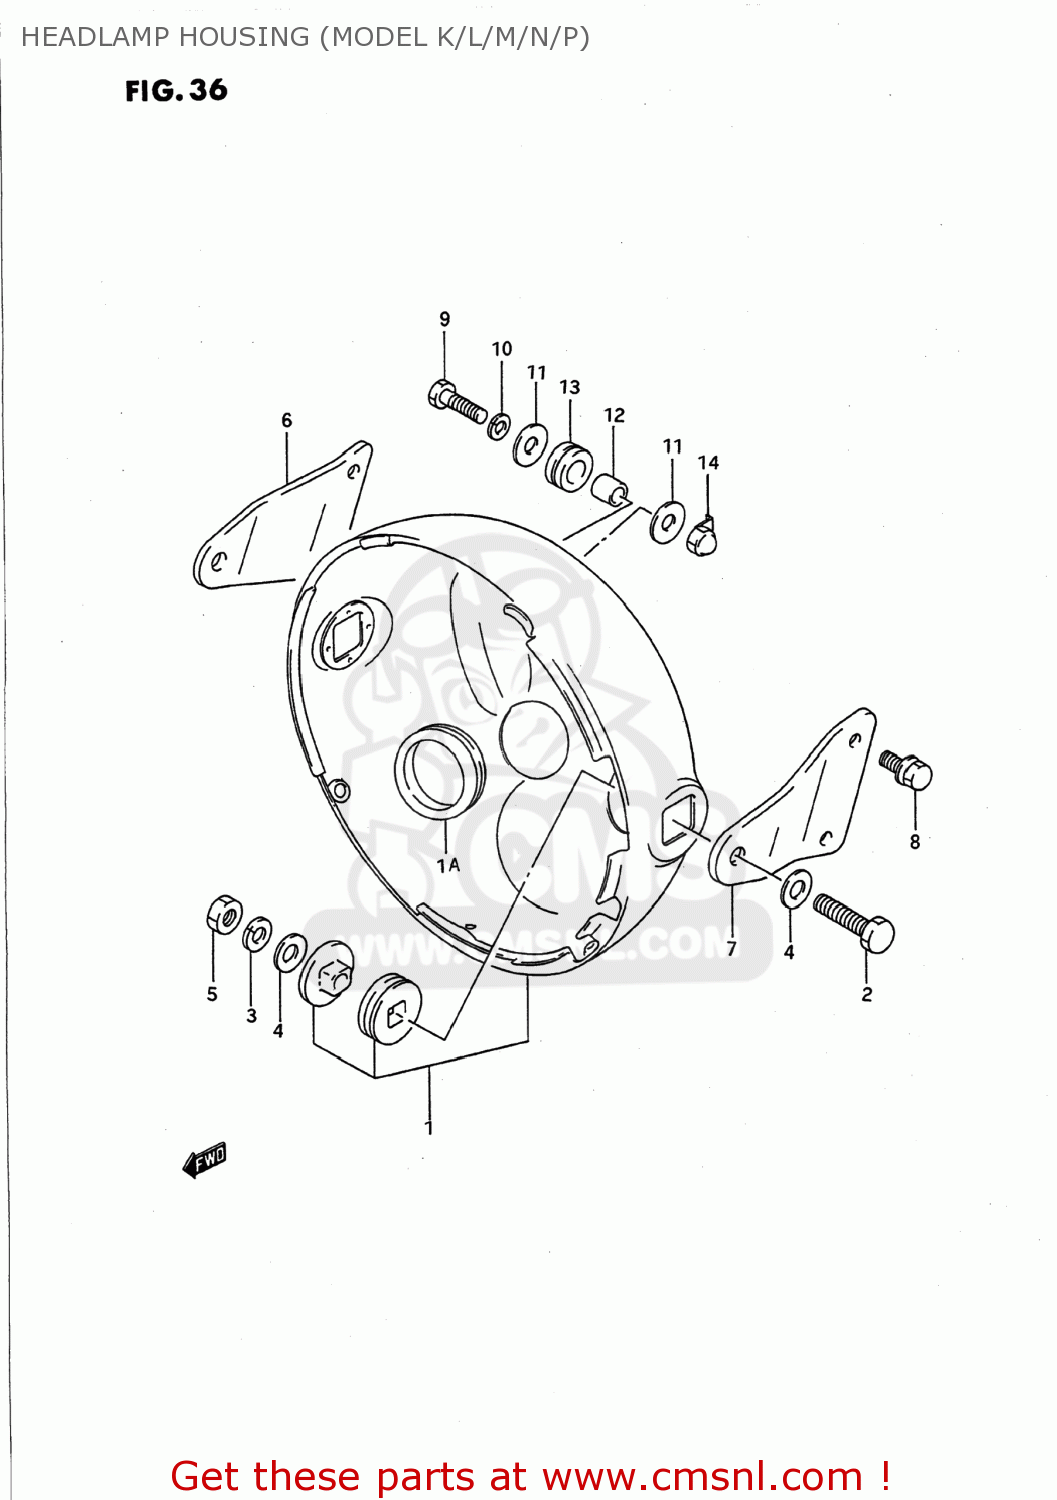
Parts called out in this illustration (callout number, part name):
1	HOUSING,HEADLAMP
1A	GROMMET
2	BOLT
3	WASHER,LOCK
4	WASHER
5	NUT
6	STAY,HEADLAMP HOUSING
7	STAY,HEADLAMP HOUSING
8	BOLT
9	BOLT
10	WASHER,LOCK
11	WASHER
12	SPACER(6.5X10.5X12)
13	CUSHION
14	PLATE,HEADLAMP
